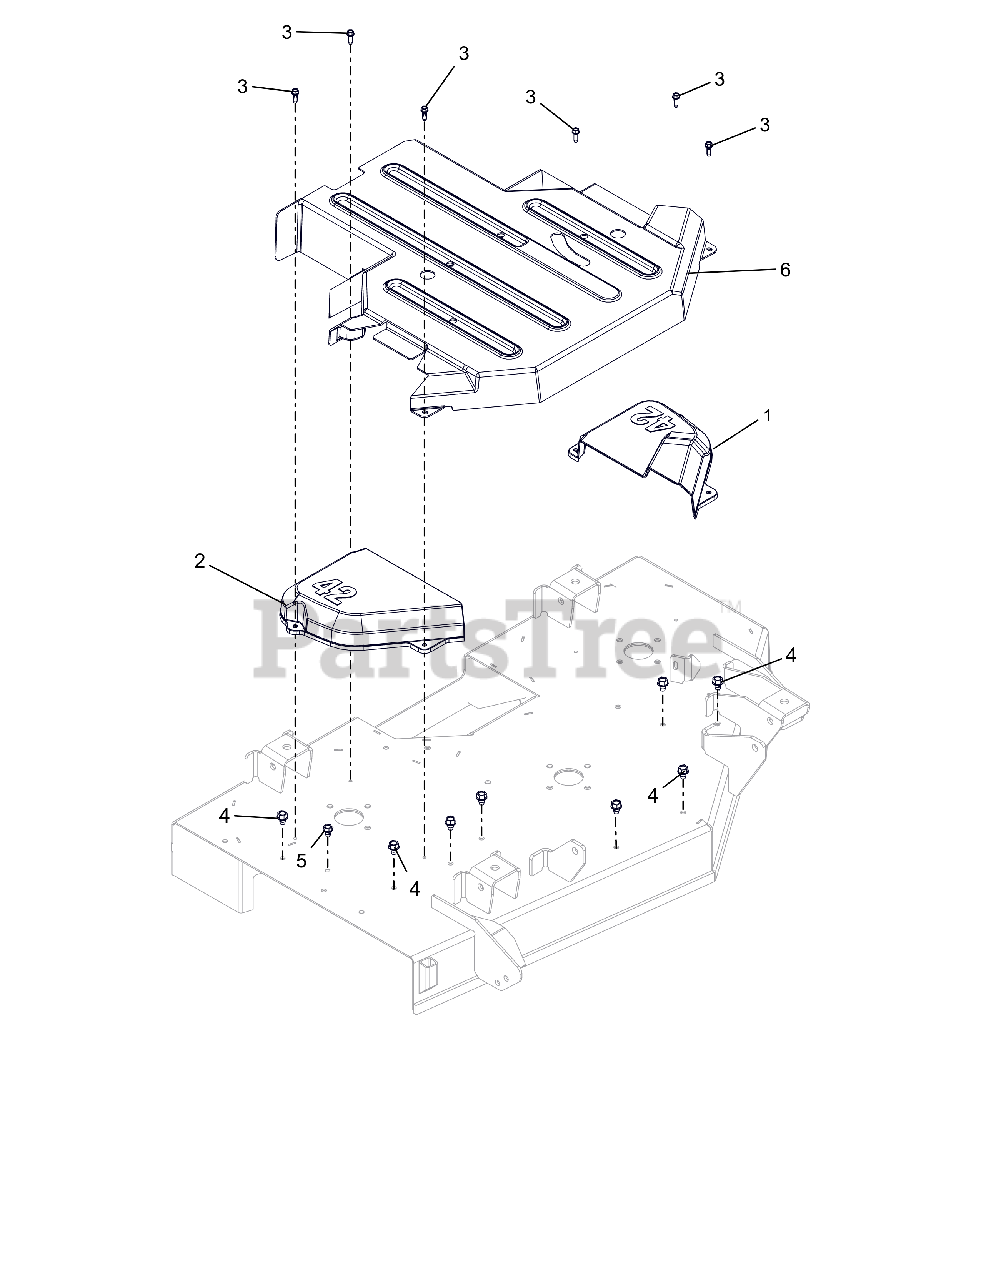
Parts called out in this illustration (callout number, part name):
1	COVER, BELT 42" LH
2	COVER, BELT 42" RH
3	SCR,TAP .25-20X.75 HWH TR ZCC
4	SCR,TAP .375-16X.50 HWH TR ZCC
5	SCR,TAP .312-18X.50 HWH TR ZCC
6	GUARD, IKON BELT-42" CE
